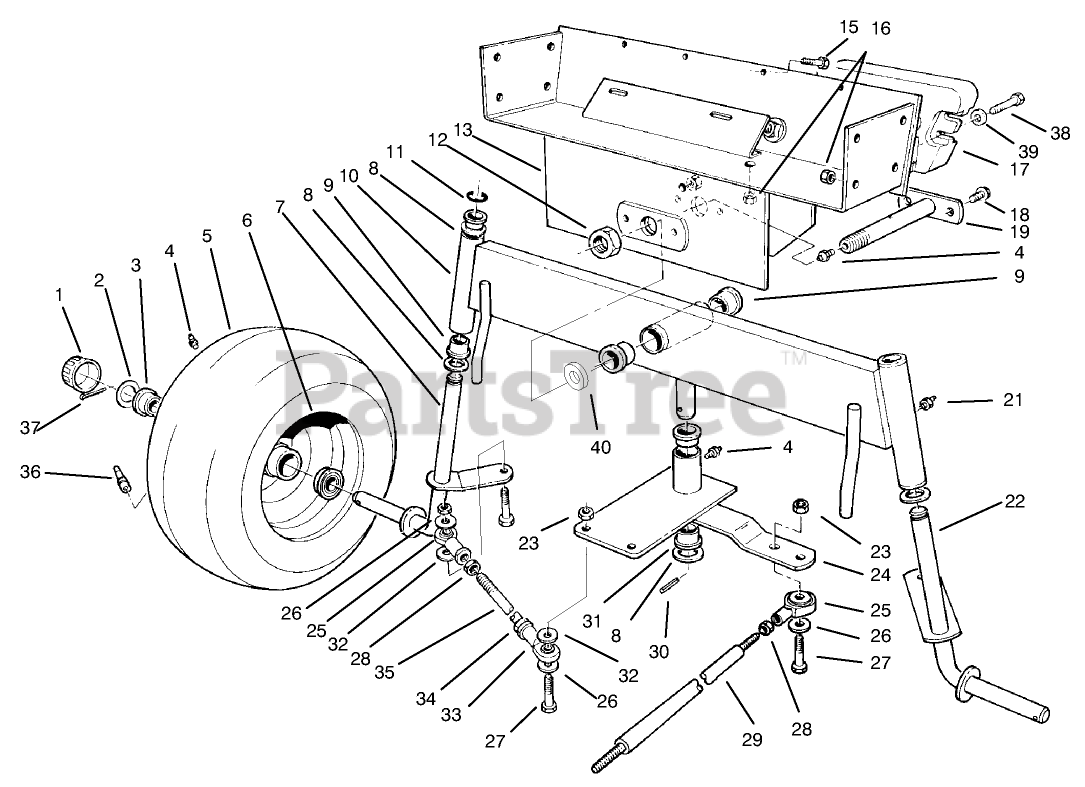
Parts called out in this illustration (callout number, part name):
1	CAP-HUB
2	WASHER-PLAIN
3	Bearing
4	FITTING-GREASE
6	FRONT WHEEL
7	Spindle R.H.
8	WASHER-THRUST
9	BUSHING PM
10	Axle-Rear (Incl. Ref. #9 & 20)
11	E-RING
12	NUT-LOCK NI
13	Frame-Rear
15	SCREW-HH
16	NUT-LOCK, NI
17	WEIGHT-REAR
18	SCREW-HHFTF
19	Axle-Pivot
21	GREASE FITTING
22	Spindle LH.
23	NUT-LOCK, NI
24	Plate- Pivot (Incl. Ref. #4 & 30)
25	BALL JOINT RH
26	WASHER-FLAT
27	SCREW-HH
28	NUT-JAM
29	Rod-Steering
30	PIN-ROLL
31	BEARING-FLANGE
32	WASHER
33	BALL JOINT LH
35	TIE ROD - STEERING
36	STEM-VALVE
37	PIN-COTTER
38	SCREW-HH
39	WASHER-LOCK
40	WASHER-FLAT
